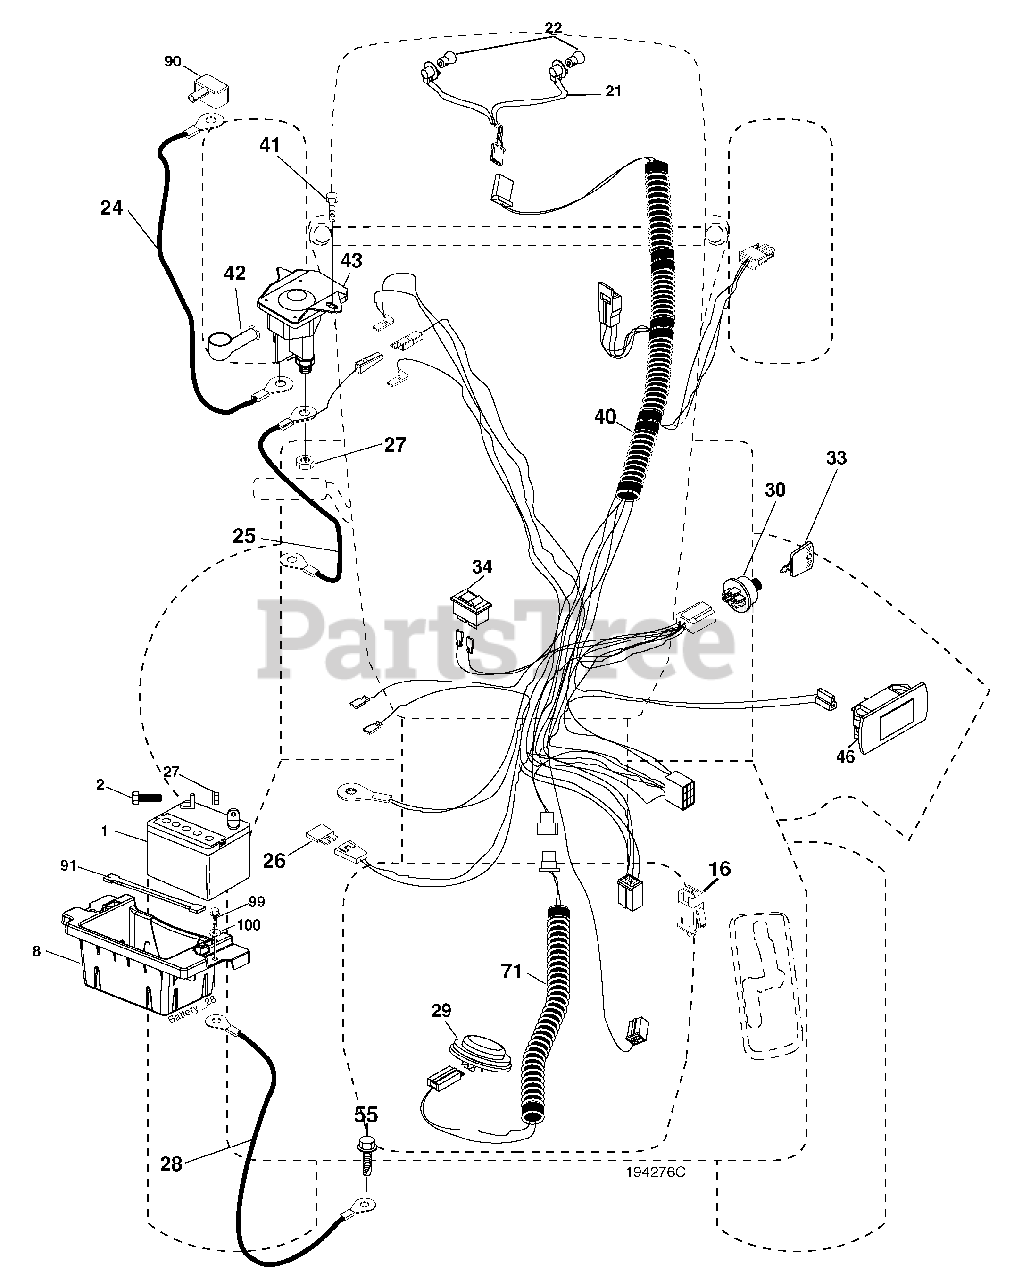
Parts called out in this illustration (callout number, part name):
1	Battery
2	Bolt Hex Head 1/4-20 x 3/4
8	Box Battery
16	Switch Interlock Push-In
21	Harness Socket Light W/4152J
22	Bulb Light
24	Cable Battery
25	Cable Starter
26	Fuse
27	Nut Keps Hex 1/4-20 unc
28	Cable, Ground
29	Switch, Seat
30	Switch, Ign
33	Key, Ignition
34	Switch Light / Reset
40	Harness Ign.
41	Screw Thd Cut 1/4-20 x 1/2
42	Cover, Terminal
43	Solenoid
46	Gauge Hourmeter
55	Screw Thdrol 5/16-18 x 3/4 TYTT
71	Harness Ign. Dash
90	Cover Terminal Battery
91	Strap Battery Mount Front
99	Screw Hexwsh Thdrol 1/4-20 x 3/4
100	Washer 9/32 x 7/8 x 16 Ga.
